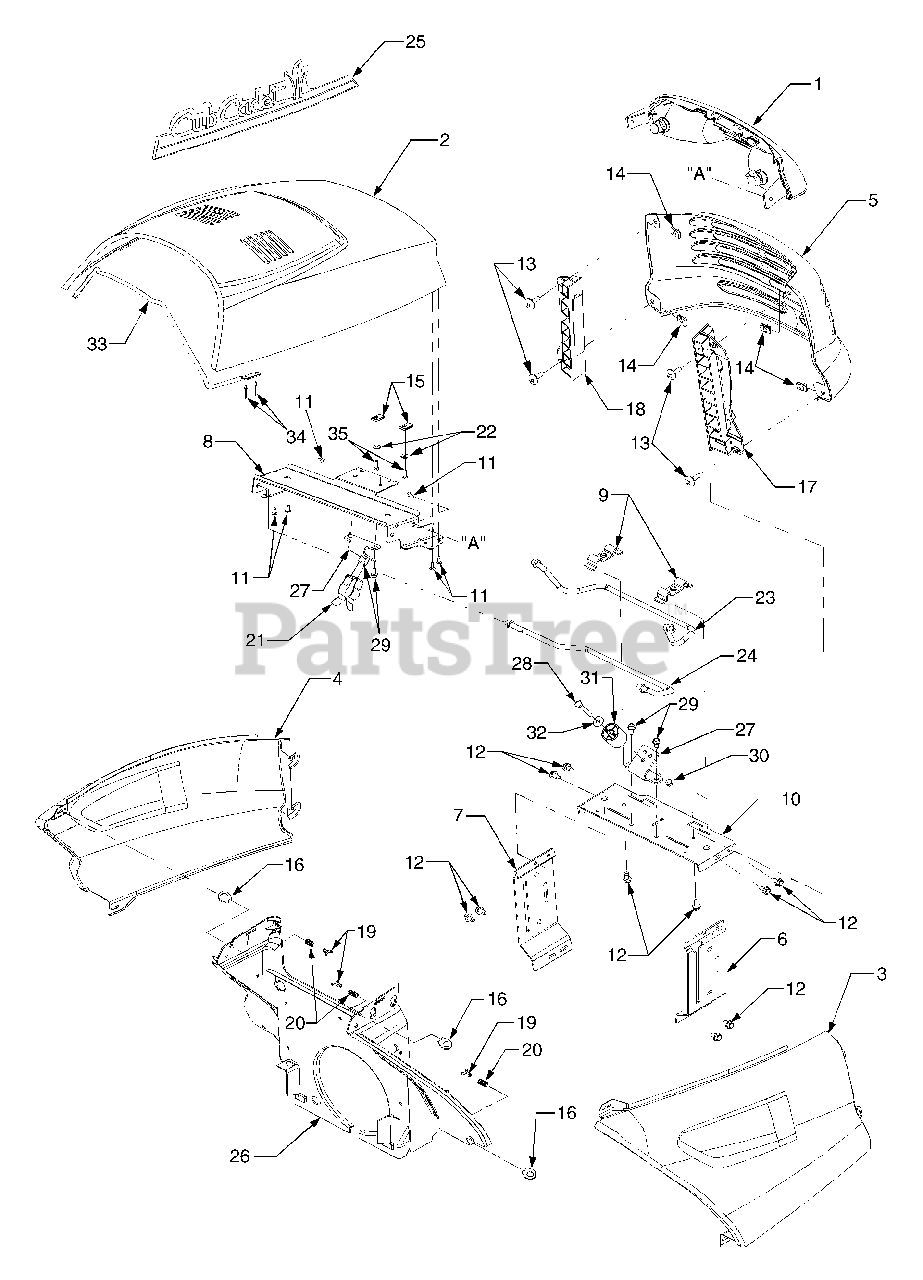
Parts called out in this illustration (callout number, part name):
1	Headlight Assembly
3	Side Panel, RH
4	Side Panel, LH
5	Grille, Series 3000
6	Support, Grille - RH - Cub Yellow
6	Support, Grille - RH - Black
7	Support, Grille - LH - Cub Yellow
7	Support, Grille - LH - Black
8	Bracket, Upper Hood
9	Bracket, Rod Retainer
10	Support, Hood - Cub Yellow
10	Support, Hood - Black
11	Screw,Truss Hd, Tapp, #10-16 x .5
12	Screw, Hex Wash. Hd. Tapp 5/16-18 x .5
13	Screw, Phil. Pan Hd. 1/4-20 x 75
14	Nut, U Type Speed, 1/4-20
15	Nut, U-type Speed, #10
16	Latch, 1/4 Turn
17	Mount, Side Panel/Grille RH
18	Mount, Side Panel/Grille LH
19	Clip, Spring
20	Spring, Compression
21	Spring, Hood Latch
22	Washer, Flat, .194 x .62 x .063
23	Rod, Upper Hood
24	Rod, Lower Hood
25	Graphic, Hood - RH 2008 & Before
25	Graphic, Hood - RH 2009 & After
25	Graphic, Hood - LH 2008 & Before
25	Graphic, Hood - LH 2009 & After
26	Baffle, Lower Air
27	Bracket, Hood Latch Support
28	Screw, Hex Cap, 1/4-20 x 1.75 GR5
29	Screw, Hex Wash Hd Tapp, 1/4-14 x 5
30	Nut, Hex Top Lock, 1/4-20
31	Roller, Hood Latch
32	Washer, Flat, .283 x .75 x .030
33	Rod, Hood Support
34	Rivet, Pop, .125 OD
35	Screw, Hex Tapp, #10-16 x .625
